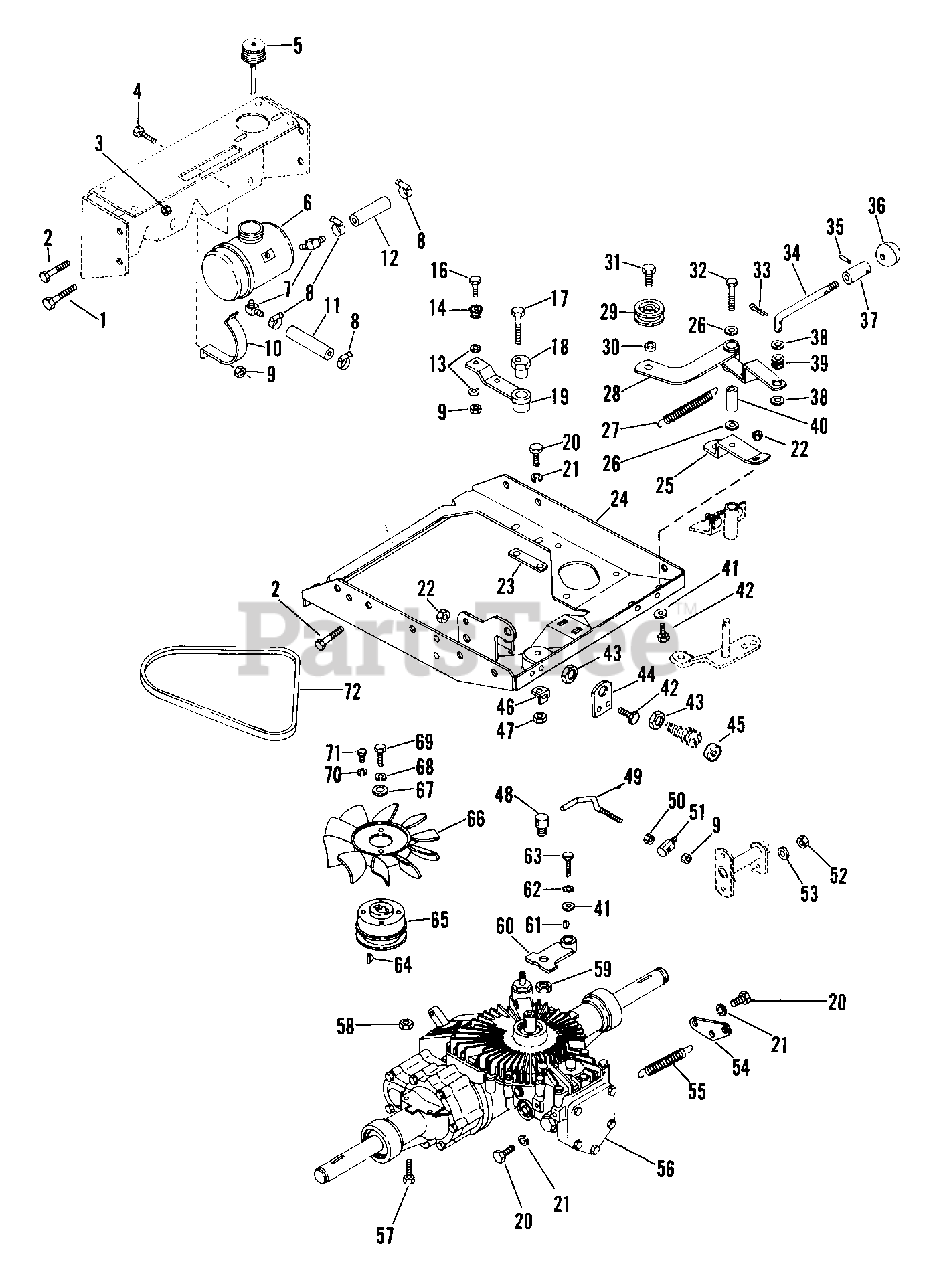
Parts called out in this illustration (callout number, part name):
1	BLT-HEX .38-16X1.00 PL GR5
2	BLT-HEX .38-16X.75 PL GR5
3	NUT-LK TOP .375-16 GR C YWZC
4	BLT-HEX .25-20X.75 PL GR2
5	CAP W/DIPSTICK
5	DIPSTICK
6	EXPANSION TANK
7	FITTING-90 DEGREES
8	HOSE CLAMP
9	NUT-LK-CTR .250-20 PL
10	TANK-STRAP
14	BRG BALL DBL .250X.638X.438
16	BLT-HEX .25-20X1.00 GR2
17	BLT-HEX .31-18X2.25 PL GR5
18	ECCENTRIC
19	DETENT ARM
20	BLT-HEX .31-18X.63 PL GR 2
21	WSHR-LK .313X.078 PL MED
22	NUT-LK-TOP .312-18 GR C PL
23	SPACER-TRANSAXLE
24	TRANSAXLE MOUNT
25	IDLER BRACKET
26	WSHR-FL-STL .328X.875X.062 PL
27	SG-TENS .080X.470X4.88 WLD 30
28	CLUTCH ARM ASSY
29	IDLER-FLAT 1.50 X .39 CLARK
30	BSHG-SLV .377X.624X.235
31	@BLT-HEX .38-16X.88 PL GR2
32	BLT-HEX .31-18X2.25 PL GR5
33	PIN-COTR .12X.75 PL
34	CLUTCH HANDLE
35	PIN-ROLL .125X.63
36	SHIFT BALL
37	SPACER-CLUTCH HANDLE
38	WSHR-FL-STL .382X.812X.062
39	GROMMET
40	SPACER .328X.624X1.516
41	WSHR-FL-STL.312X.734X.065PL
42	BLT-HEX .31-18X.75 PL GR5
43	NUT-HEX .625-32 PL
44	SWITCH BRACKET
46	SPRING ANCHOR
47	NUT-LK-NYL.312-18 PL
48	ADAPTER
50	NUT-HEX .250-20 PL
51	ROD PIVOT
52	NUT-HEX .250-20 PL
53	WSHR-FL-STL .323X.625X.062 PL
54	SPRING ANCHOR
55	SG-TENS .091X.56X4.25 WLD 40
56	TRANSAXLE-HYDRO
56	TRANSAXLE, REBUILT
57	BLT-HEX .38-16X2.75 PL GR5
58	NUT-LK TOP .375-16 GR C YWZC
59	NUT-LK-CTR .50-13
60	SHIFT ARM
61	KEY-WDRF .125X.500X.203 SAE 3
62	WSHR-LK-EXT. 250 ID
63	BLT-HEX .25-20X1.25 PL GR5
64	KEY-WDRF .188X.625X.25 SAE 61
65	SHEAVE - TRANSAXLE
67	WSHR-FL-STL .328X1.0X.094 PL
68	WSHR-LK .250X.077 HVY PL
69	BLT-HEX .25-20X.75 PL GR5
70	WSHR-LOCK EXT #10 ID
71	BLT-HEX 10-24X.38 PL GR2
72	V-BELT, SAE 380-RAW EDGE
